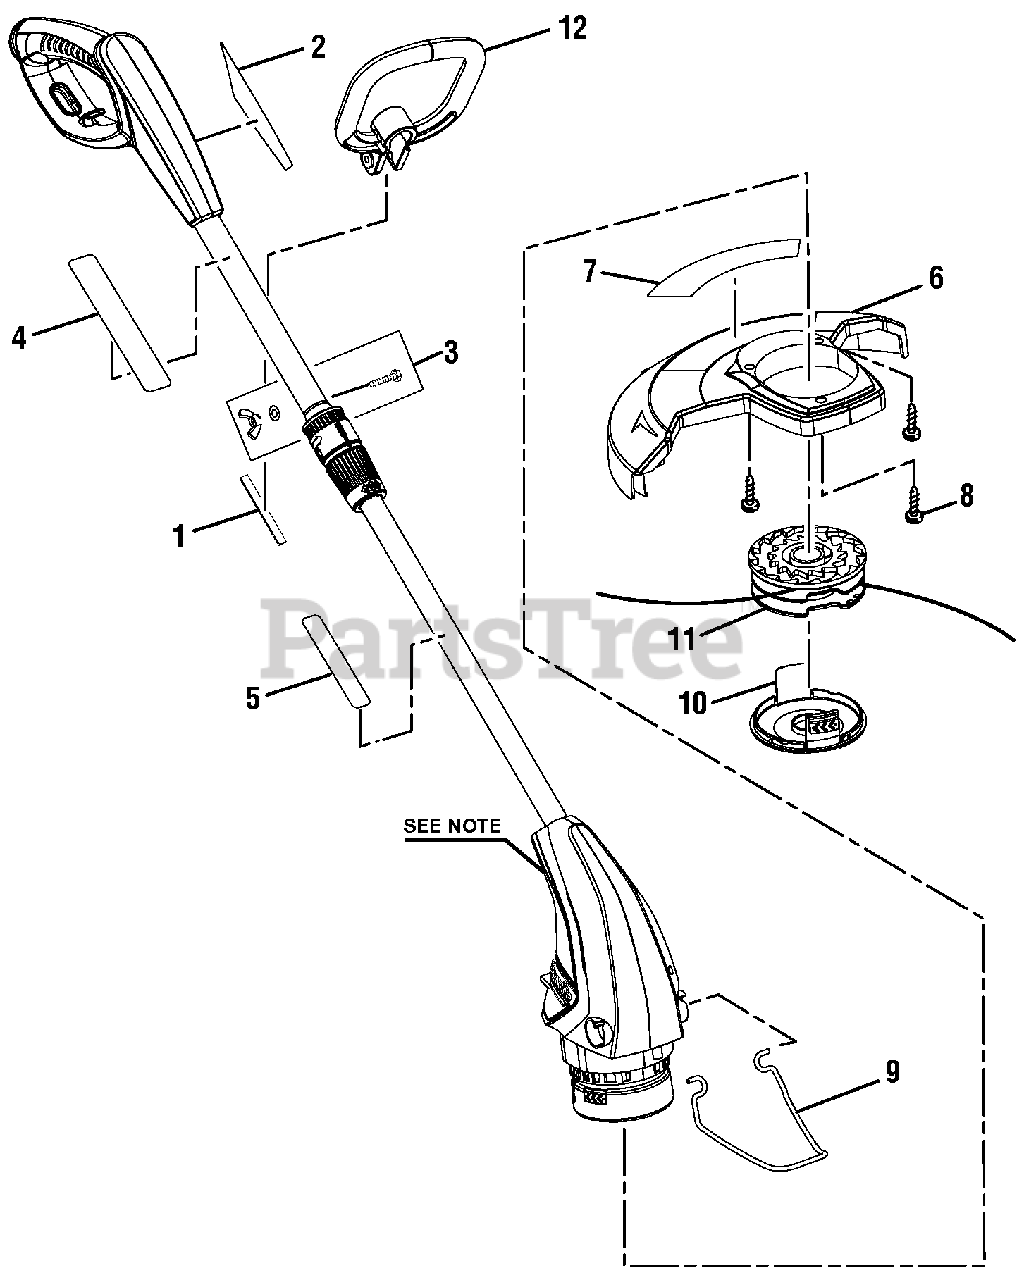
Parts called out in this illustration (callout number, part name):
1	Rubber Bumper
2	Data Label
3	Fastener Kit
4	Warning Icon Label
5	Warning Label
6	Grass Deflector
7	Grass Deflector Label
8	Screw (M4.2 x 15 mm)
9	Edge Guide
10	Spool Cap
11	Spool
12	Front Handle Assembly
